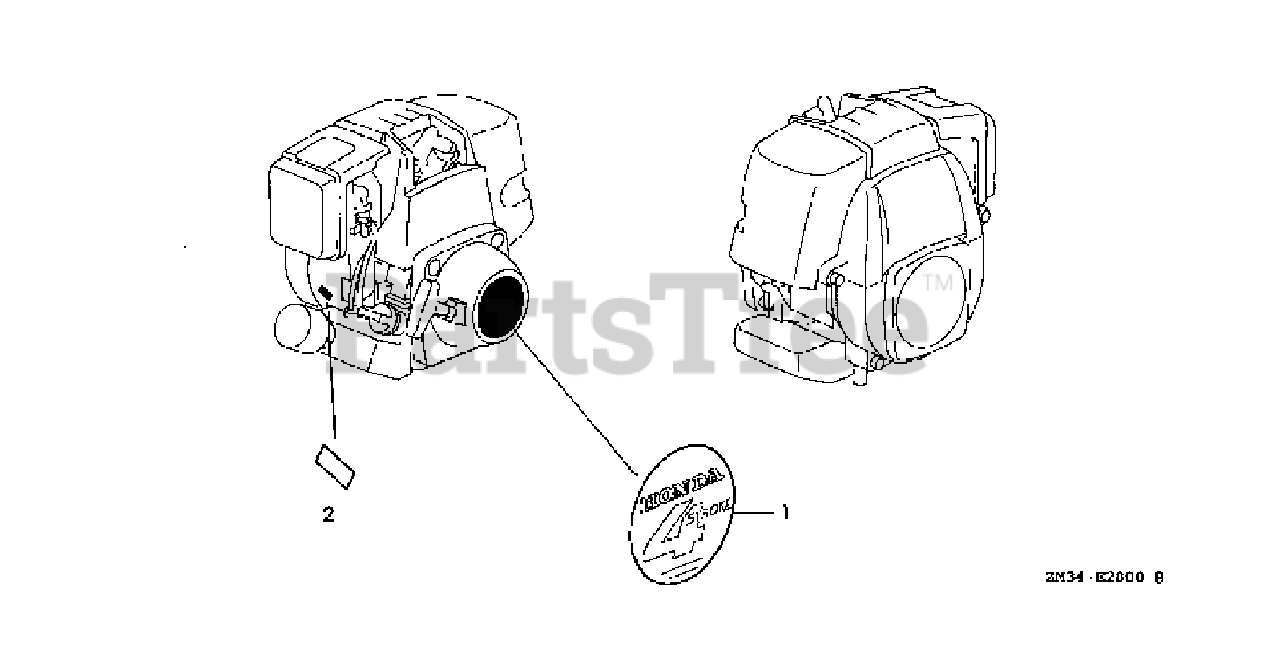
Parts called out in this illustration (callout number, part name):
1	EMBLEM (GX31)
2	MARK, TYPE (SAT)
2	MARK, TYPE (SA)
